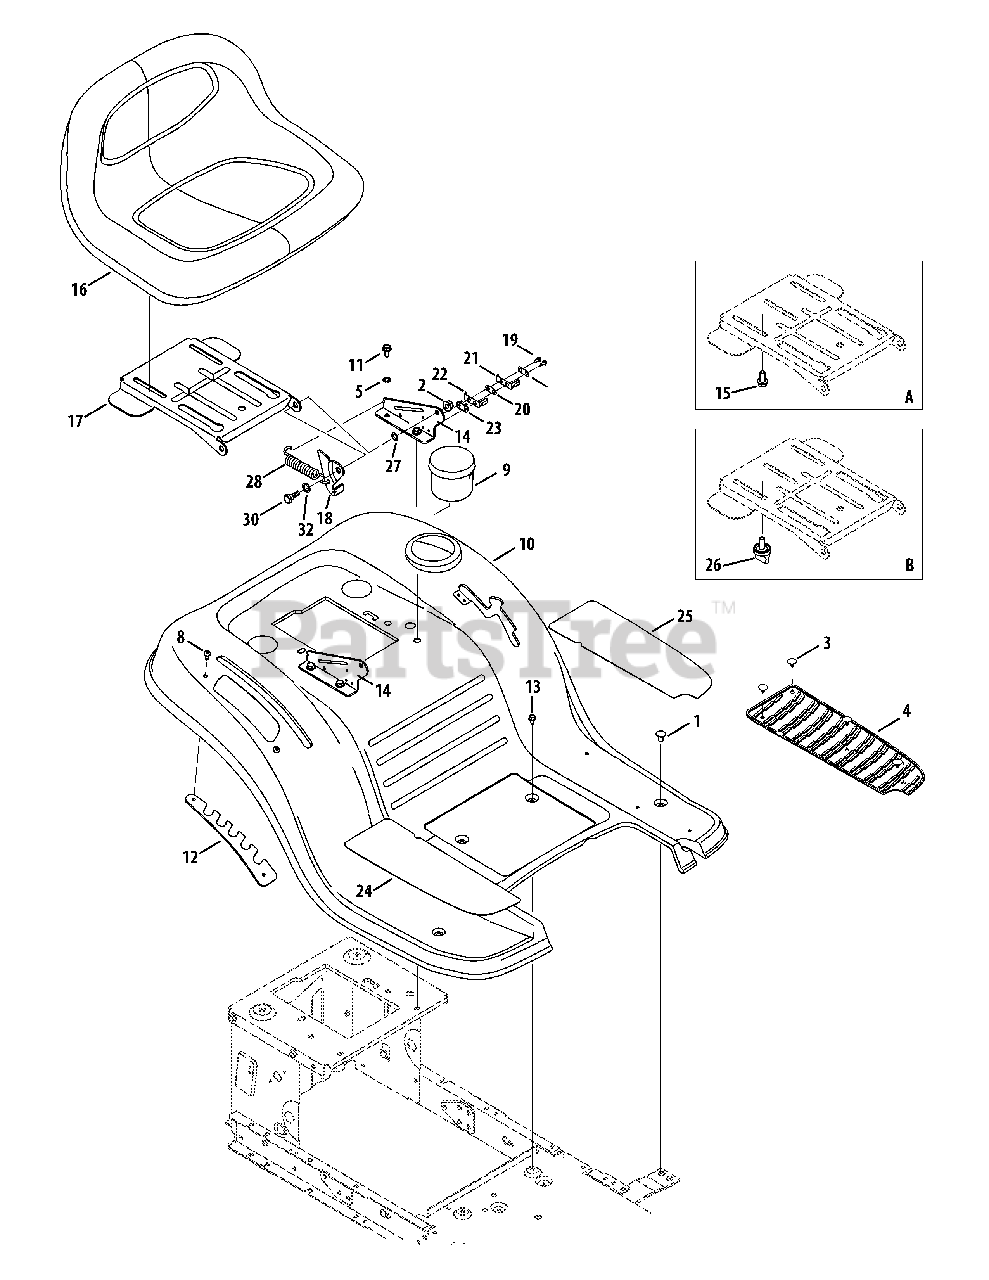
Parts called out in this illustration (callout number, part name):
1	Carriage Bolt 1/4-20 x .62
2	Flange Locknut 5/16-18 Gr. F, Nylon
3	Ratchet Clip
4	Foot Pad, RH
4	Foot Pad, LH
5	Lockwasher 5/16 ID
6	Flat Washer .510 x .750 x .033
8	Tap Screw 1/4-20 x .50
9	Cup Holder
11	S-Tapp Scr 5/16-18 x .75
12	Lift Adjustment Bracket Orange
13	Hex Wash S-Tapp Scr 1/4-20 x .50
14	Seat Mounting Bracket Orange
15	Screw 3/8-16 x .875
16	Seat, Medium Back
17	Seat Pivot Bracket Orange
18	Seat Lift Bracket
19	Hex Wash HD AB S-Tapp Scr #8-.50
20	Insulator Plate
21	Spring Switch
22	Seat Spring Switch
23	Insulator Plate
24	Foot Pad, Abrasive, RH
25	Foot Pad, Abrasive, LH
27	Cupp. Washer .345 ID x .88 OD x .060
28	Extension Spring .84 Dia. x 4.6
30	Shoulder Screw
32	Flat Washer .510 x .75 x .033
